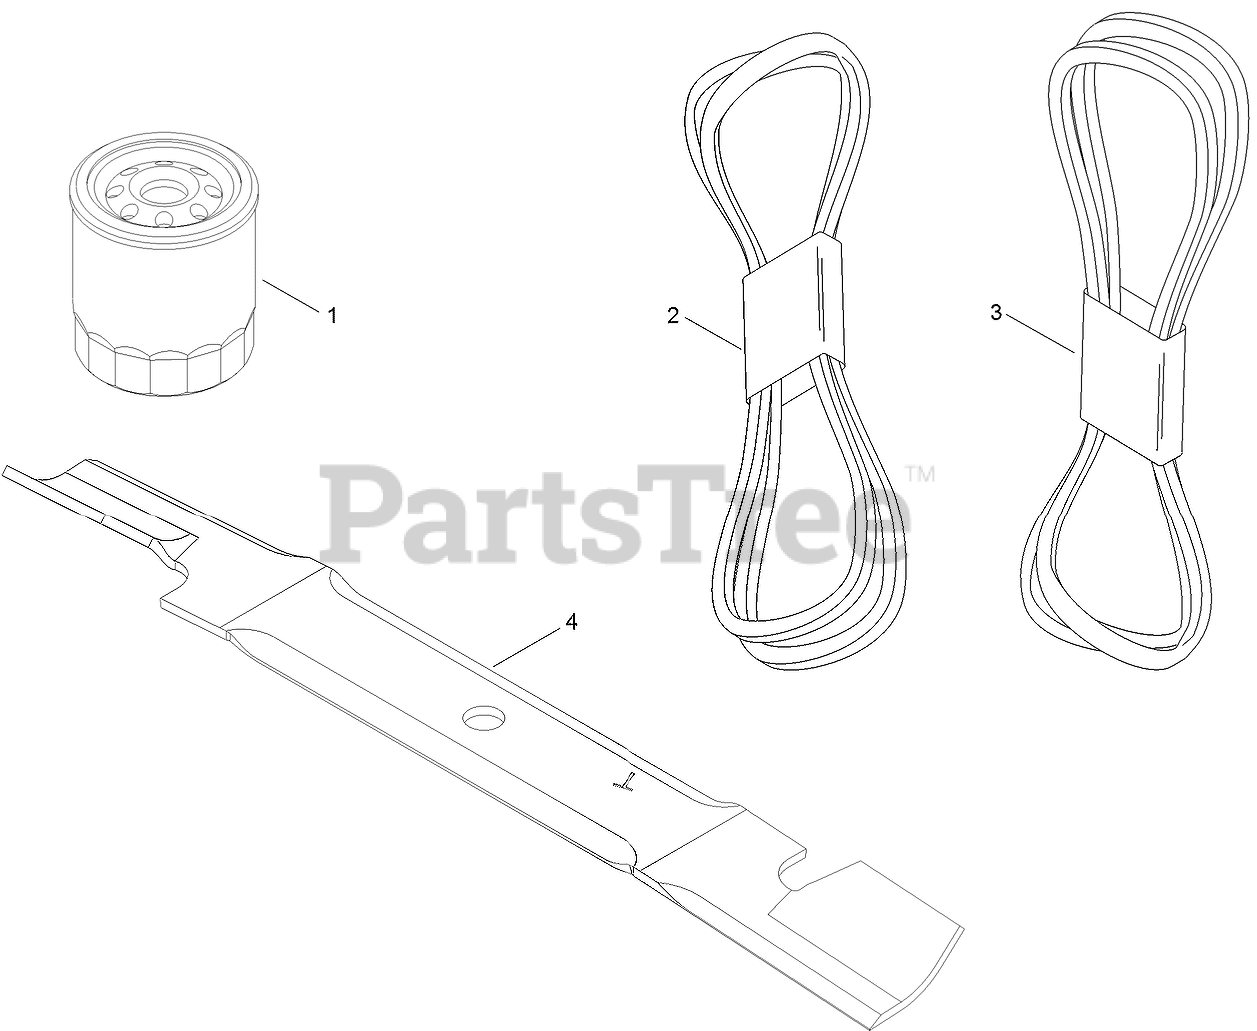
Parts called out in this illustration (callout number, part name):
1	ELEMENT-OIL FILTER, HYD
2	V-BELT
3	V-BELT
4	BLADE-HI FLO
